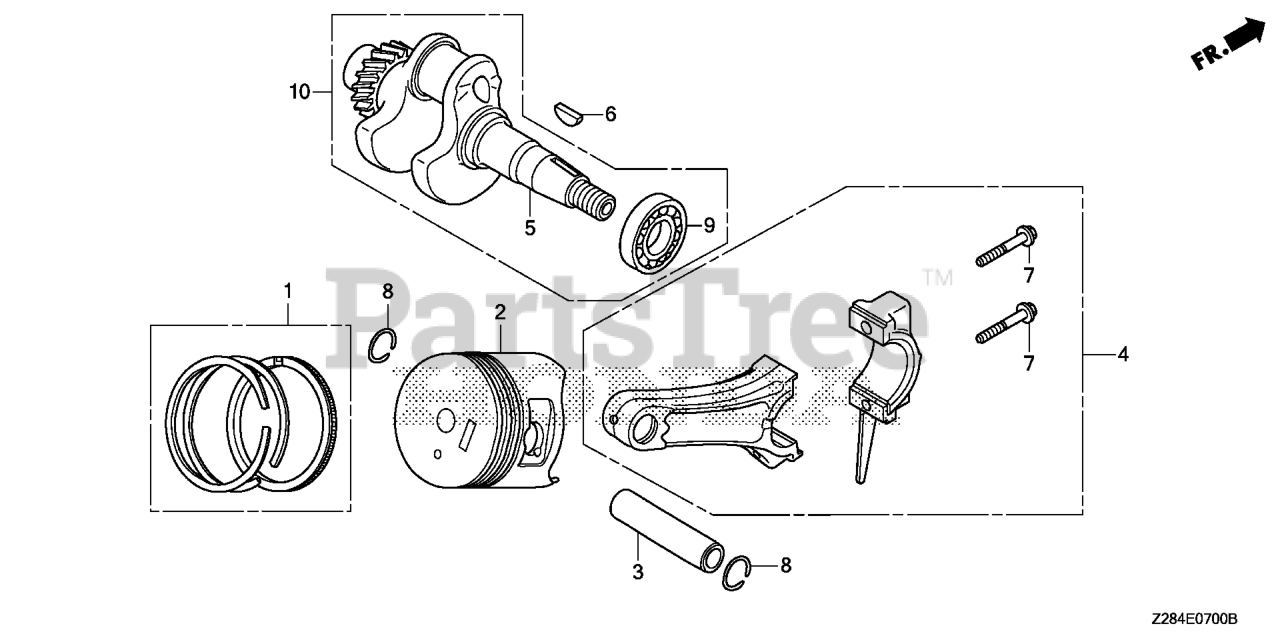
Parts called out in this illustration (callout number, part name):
1	RING SET, PISTON (STD) (TPR)
1	RING SET, PISTON (0.25) Use from Engine SN 1314913.
1	RING SET, PISTON (0.50) (TPR)
1	RING SET, PISTON (0.75) Use from Engine SN 1314913.
2	PISTON (STD)
2	PISTON (0.25) Use from Engine SN 1314913.
2	PISTON (0.50) Use from Engine SN 1314913.
2	PISTON (0.75) Use from Engine SN 1314913.
3	PIN, PISTON
4	ROD ASSY., CONNECTING (STD)
4	ROD ASSY., CONNECTING
5	CRANKSHAFT
6	KEY, SPECIAL WOODRUFF (25X18)
7	BOLT, CONNECTING ROD
8	CLIP, PISTON PIN (18MM)
